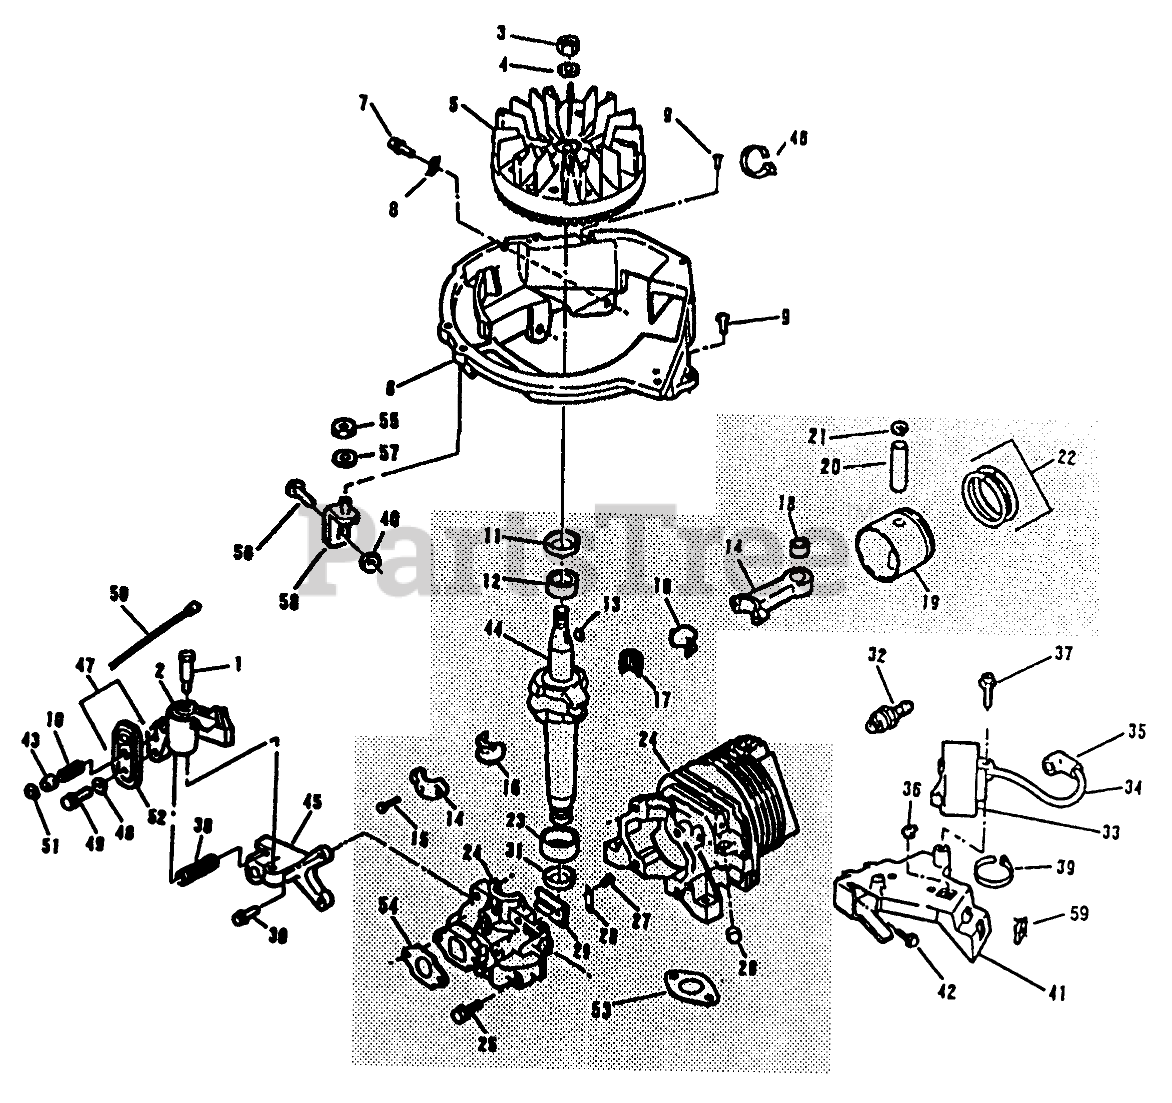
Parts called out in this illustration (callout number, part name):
1	SCREW-SHOULDER
2	BRAKE AY FE
3	NUT
4	WASHER-LOCK
5	FLYWHEEL ASSY F
6	BASE SHROUD F
7	SCREW F
8	"J" CLIP F
9	SCREW F
10	SPRING
11	SEAL-OIL
12	BEARING V
13	KEY
15	SCREW-HSH
16	LINER ASM
17	BEARING-NEEDLE
18	BEARING AY F
20	PIN-WRIST VF
21	RING-RETAINING
22	F-RING SET
23	BEARING V
24	CYL.C'CASE AY S
25	SCREW-H.W.HD. F
26	PLUG-CORE VF
27	SCREW-HH
28	PLATE-BACKUP, REED
29	REED-CARBURETOR
30	SCREW
31	SEAL-OIL
32	Spark Plug
33	Module-C.D. Ignition & Lead
34	HT LEAD&COVER XEV
36	NUT-CLIP
37	SCREW F
38	SPRING-BRAKE
39	TIE-CABLE
40	NUT-LOCK F
41	C.D. BRKT F
42	SCREW F
43	ACTUATOR-LEVER, BRAKE
44	Crankshaft
45	BRACKET-BRAKE F
46	STRAP-TIE
47	Switch Kit
48	WASHER
49	Screw
50	WIRE LEAD AY F
51	RETAINER S
52	Assembly-Case
53	Gasket
54	GASKET CARB S
55	LOCKNUT E
56	BOLT F
57	WASHER
58	BRACE AY F
59	NUT-SPEED
